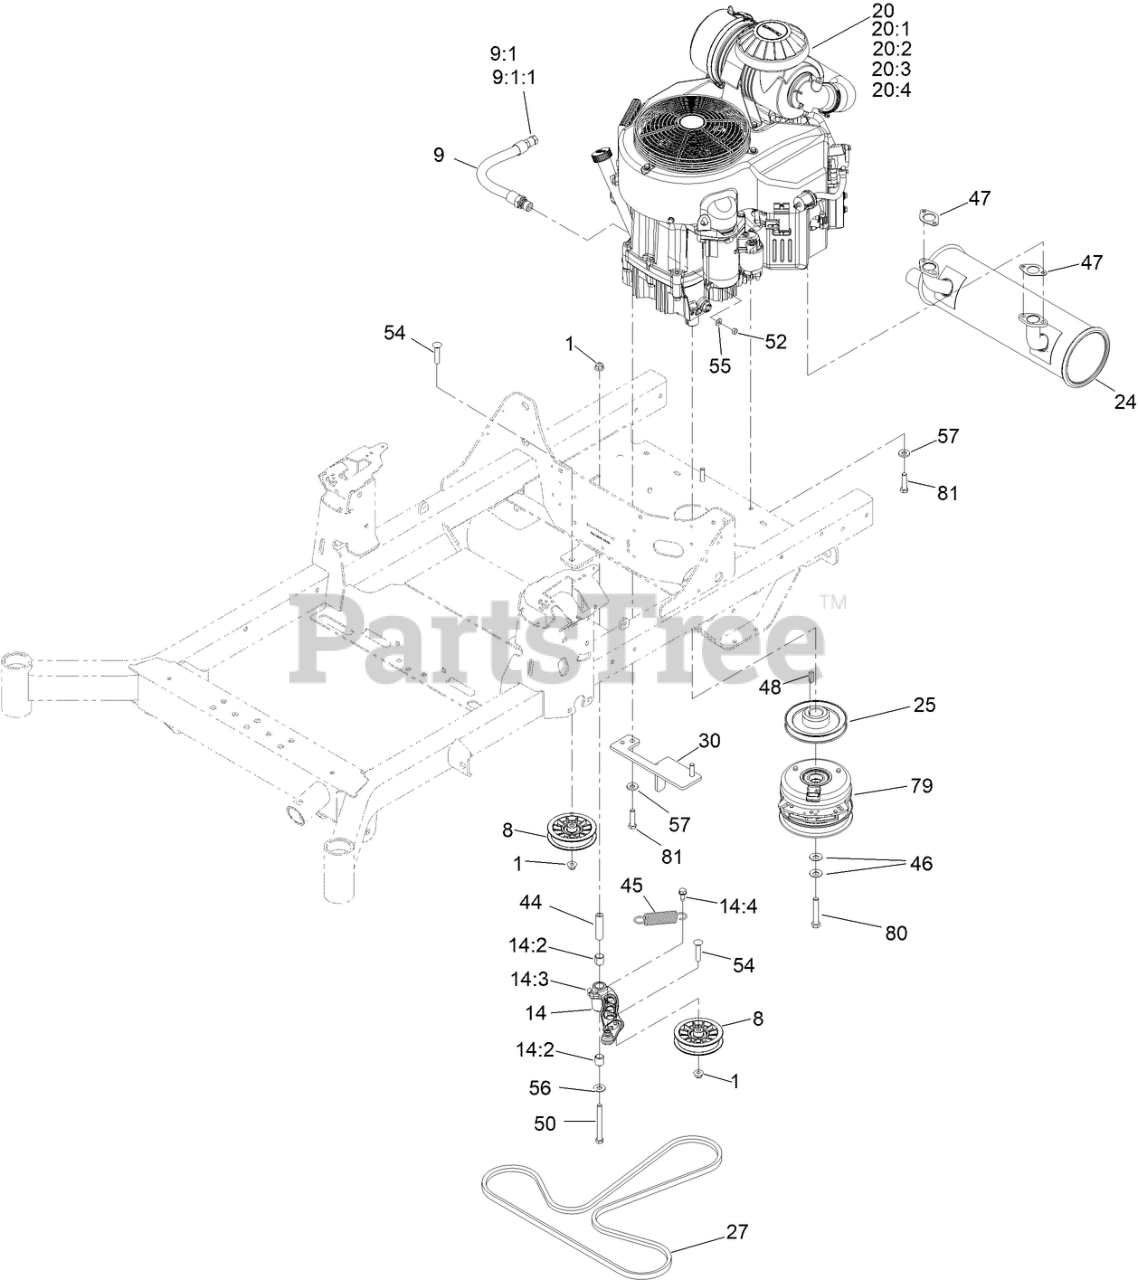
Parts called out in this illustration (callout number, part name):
1	NUT-HF, NI
8	PULLEY-FLAT IDLER
9	ENGINE OIL DRAIN HOSE ASM
9:1	PLUG-HH
9:1:1	O-RING
14	IDLER ARM ASM
14:2	SLEEVE-BEARING
14:3	FITTING-GREASE, 90 DEG
14:4	SCREW-THD ROLL, HWH
20	ENGINE-KAWASAKI, FX751V-S07-R
20:1	KAWASAKI 49065-2078 ENGINE OIL FILTER
20:2	KAWASAKI 49019-0031 FUEL FILTER
20:3	KAWASAKI 11013-7039 SAFETY FILTER
20:4	KAWASAKI 11013-7038 AIR FILTER
24	MUFFLER
25	SHEAVE (W/HUB)
27	BELT-V
30	ANCHOR-CLUTCH
44	BUSHING-PIVOT, IDLER
45	SPRING-EXTENSION
46	WASHER-SPRING
47	GASKET-EXHAUST
50	SCREW-HH
52	NUT-HEX
54	SCREW-CARR
55	WASHER-FLAT
56	WASHER-FLAT
57	WASHER-BELLEVILLE
79	CLUTCH-PTO
80	SCREW-HH
81	SCREW-HH
